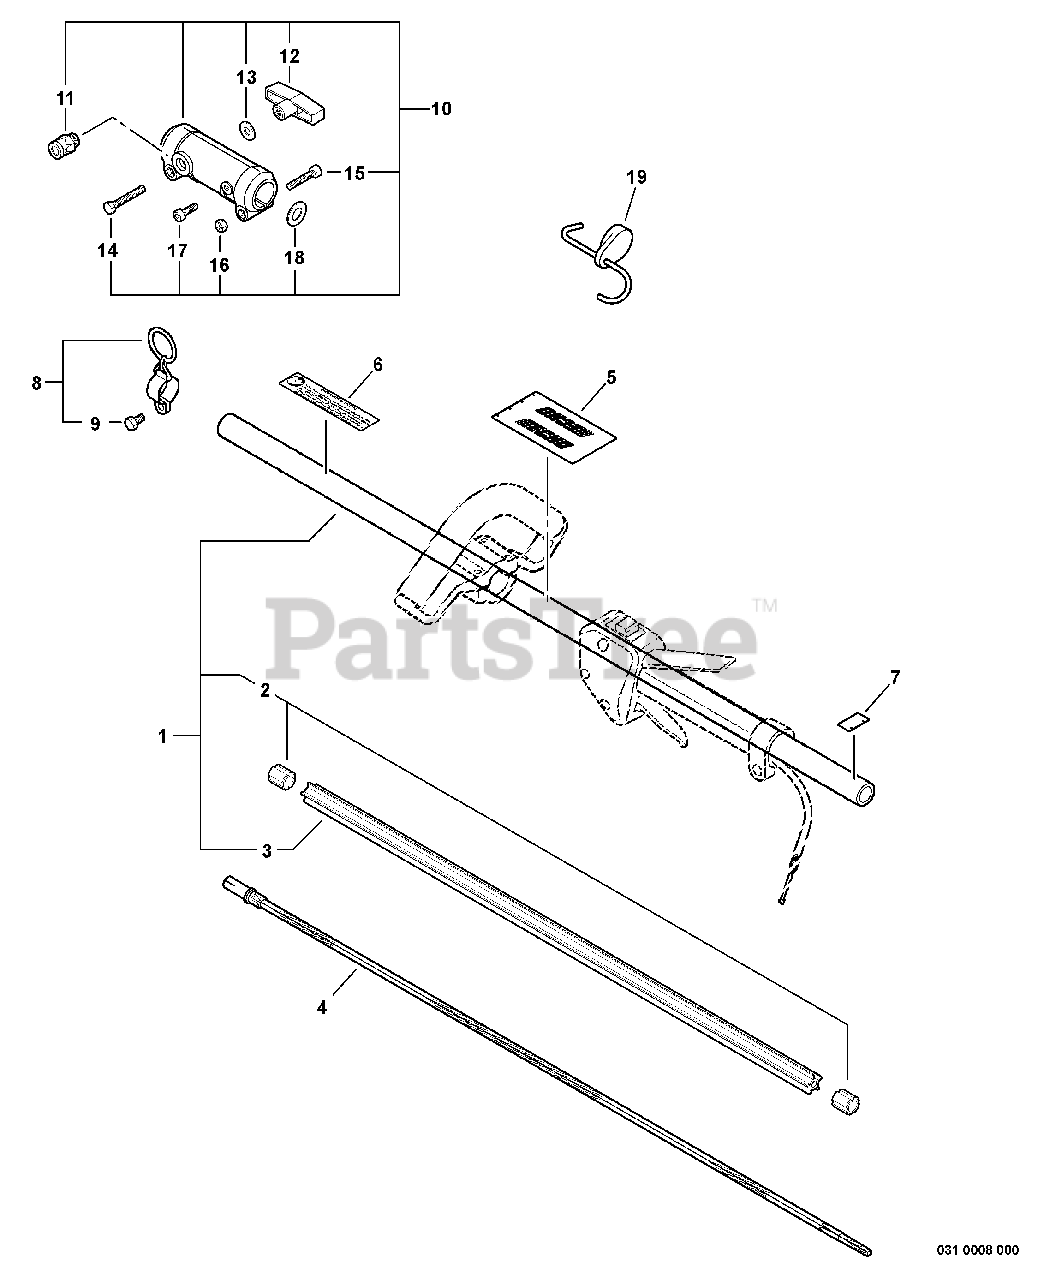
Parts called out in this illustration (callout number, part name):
1	MAIN PIPE ASSY
3	LINER - FLEXIBLE
4	DRIVESHAFT - FLEXIBLE
5	LABEL - HANDLE LOCATION
6	LABEL - CAUTION -- SPANISH
7	LABEL - ALIGNMENT
8	HANGER KIT
9	BOLT - 5X12
10	COUPLER ASSY
11	LATCH ASSY
12	WINGNUT
13	WASHER - 6
14	BOLT - 6X40
15	SCREW - 6X25
17	SCREW - 6X10
18	WASHER - 18
